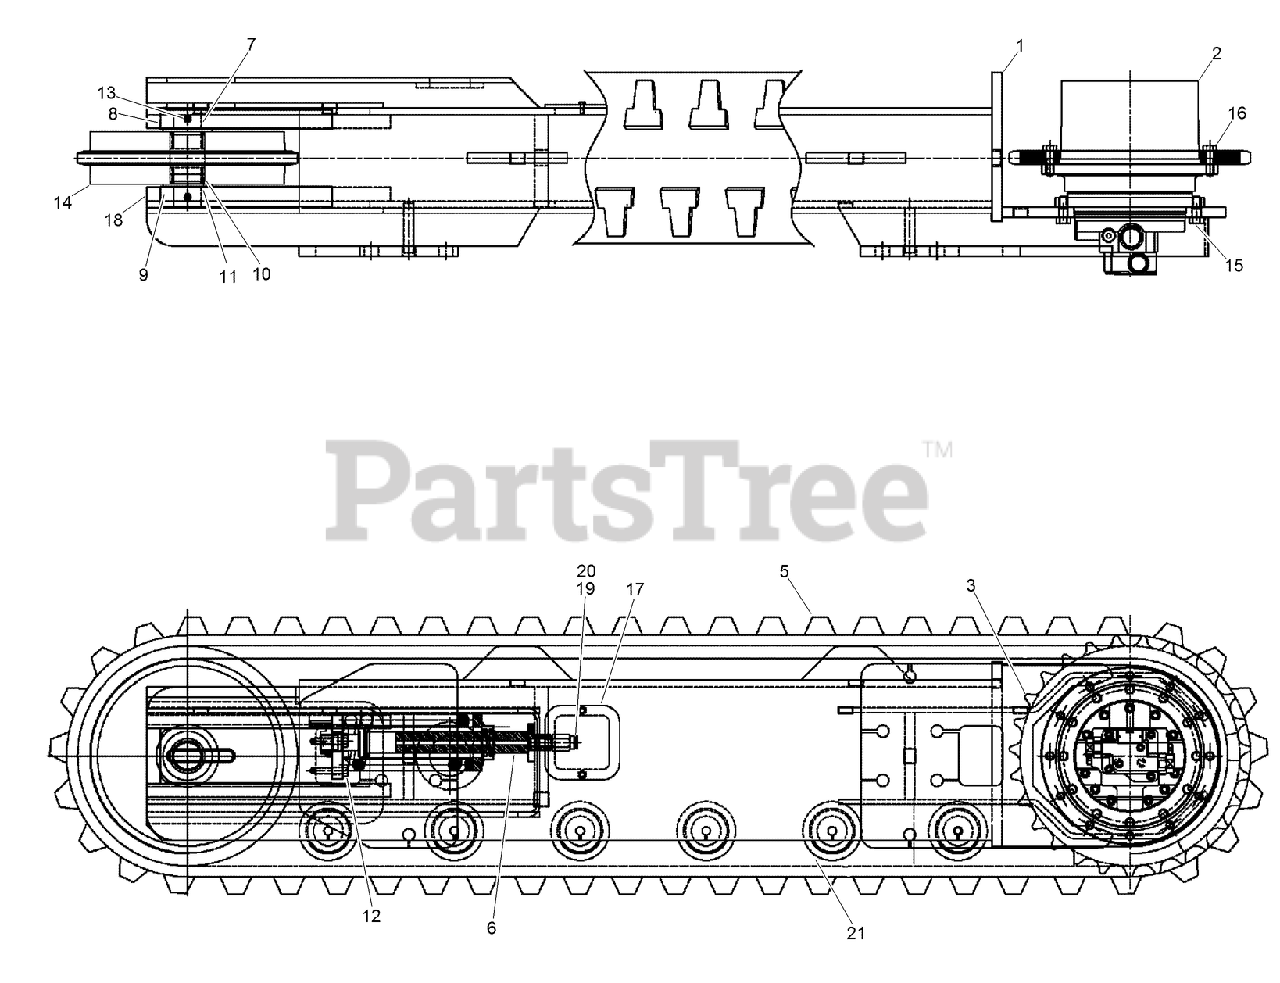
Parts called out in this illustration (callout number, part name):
1	WELDMENT - Track Drive, Left Hand
2	PLANETARY GEARBOX ASM
3	SPROCKET - Drive, Track, 27 Tooth
5	TRACK-RUBBER
6	TENSIONER-TRACK
7	PIN-AXLE
8	SLIDER - Tensioner Bar, 1-1/2 x 4 x 12-11/16 Long
9	BEARING-THRUST
10	BEARING - Roller, without Inner Ring, 2.00 ID x 2.562 OD
11	SEAL-SHAFT
13	PIN-SLOTTED, SPRING
14	SPROCKET - Idler, 16-1/4 OD x 4 Thk
15	SCREW-HH
16	SCREW-HH
17	COVER - Access Opening
18	SLIDER - Tensioner Bar, 1-1/2 x 4 x 12-11/16 Long
19	FITTING - Grease, Giant Button Head
20	WASHER - Copper, Seal.
21	ROLLER-TRACK
